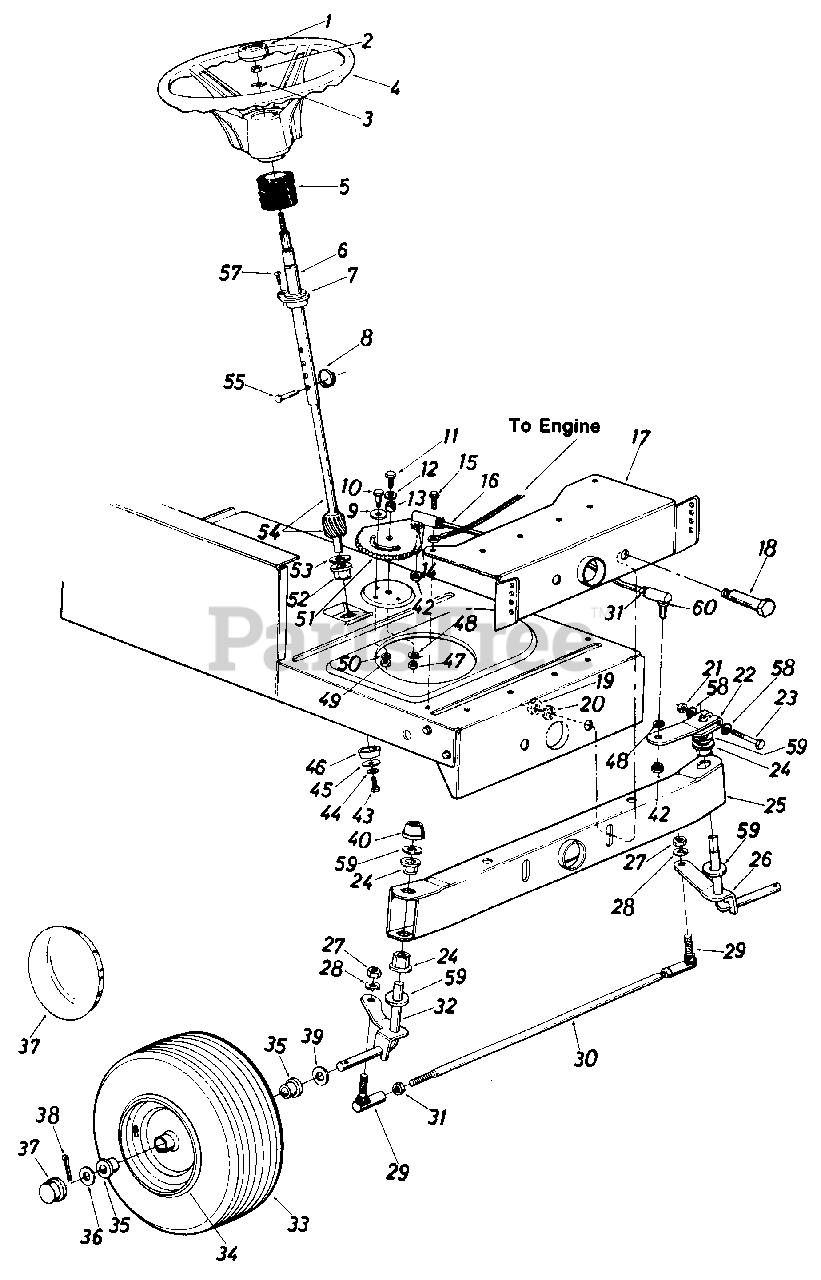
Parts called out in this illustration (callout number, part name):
1	Steering Wheel Cap
2	Hex Nut 5/16-18 Thd.
3	Belleville Wash. .345" I.D.
4	Steering Wheel 12" Dia.
5	Steering Bellow-4.5"
6	Steering Column Ass'y.
7	Flange Bearing .890 I.D. x 1.36 O.D.
8	Locking Ring
9	Fl-Wash. .438" I.D. x 1.37" O.D.
10	Shoulder Bolt .437" Dia. x .35 Lg. 5/16-18 Thd.
11	Hex Bolt 3/8-24 x 1.0" Lg. (Grade 5)
12	Fl-Wash. .38" I.D. x 1.0" O.D.
13	Spacer .380" I.D. x .625" O.D. x .227
14	L-Wash..38" I.D.*
15	Hex Wash. Hd. Self-Tap Scr.
16	Steering Drag Link
17	Front Pivot Brkt.
18	Shoulder Bolt .498" Dia. x 2.04 Lg. 3/8-16 Thd.
19	Hex Nut 3/8-16 Thd.
20	L-Wash. 3/8" I.D.*
21	Hex Cent. L-Nut 5/16-24 Thd.
22	Steering Arm Front Axle
23	Hex Bolt 5/16-24 x 2.00" Lg. (Grade 5)
24	Hex Flg. Brg. .634 I.D.
26	Front Axle Ass'y.-L.H.
27	Hex Nut 3/8-24 Thd.
28	L-Wash. 3/8" I.D.*
29	Ball Joint 3/8-24 Thd.
30	Tie Rod
31	Hex Jam Nut 3/8-24 Thd.
32	Front Axle Ass'y.-R.H.
33	Wheel Ass'y. Comp.
34	Front Wheel Rim Only
35	Bearing
36	Fl-Wash. .635 I.D. x 1.59" O.D.
37	Front Wheel Hub Cap
38	Cotter Pin 1/8" Dia. x 1.25"*
39	Fl-Wash. .640" I.D. x 1.24" O.D.
40	Push Cap 5/8" Dia. Rod
42	Hex Nut 3/8-24 Thd.
43	Hex L-Bolt 5/16-18 x .62"*
44	L-Wash. 5/16" I.D.*
45	Fl-Wash. .344" I.D. x 1.25" O.D.
46	Spacer (Plastic)
47	Hex Nut 3/8-24 Thd.
48	L-Wash. 3/8" I.D.*
49	Hex Nut 5/16-18 Thd.
50	L-Wash. 5/16" I.D.*
51	Steering Gear Segment
52	Hex Flg. Brg. .634 I.D.
53	Fl-Wash. (Hardened)
54	Steering Shaft Lower
55	Clevis Pin 1/4" Dia. x 1.0"
57	Oval Hd. Cr.-Sunk Scr. #10 x 5/8" Lg.
58	Wave-Wash. .32" I.D. x .62" O.D.
59	Fl-Wash. (Hardened)
60	Drag Link Ball Joint 3/8-24 Thd.
